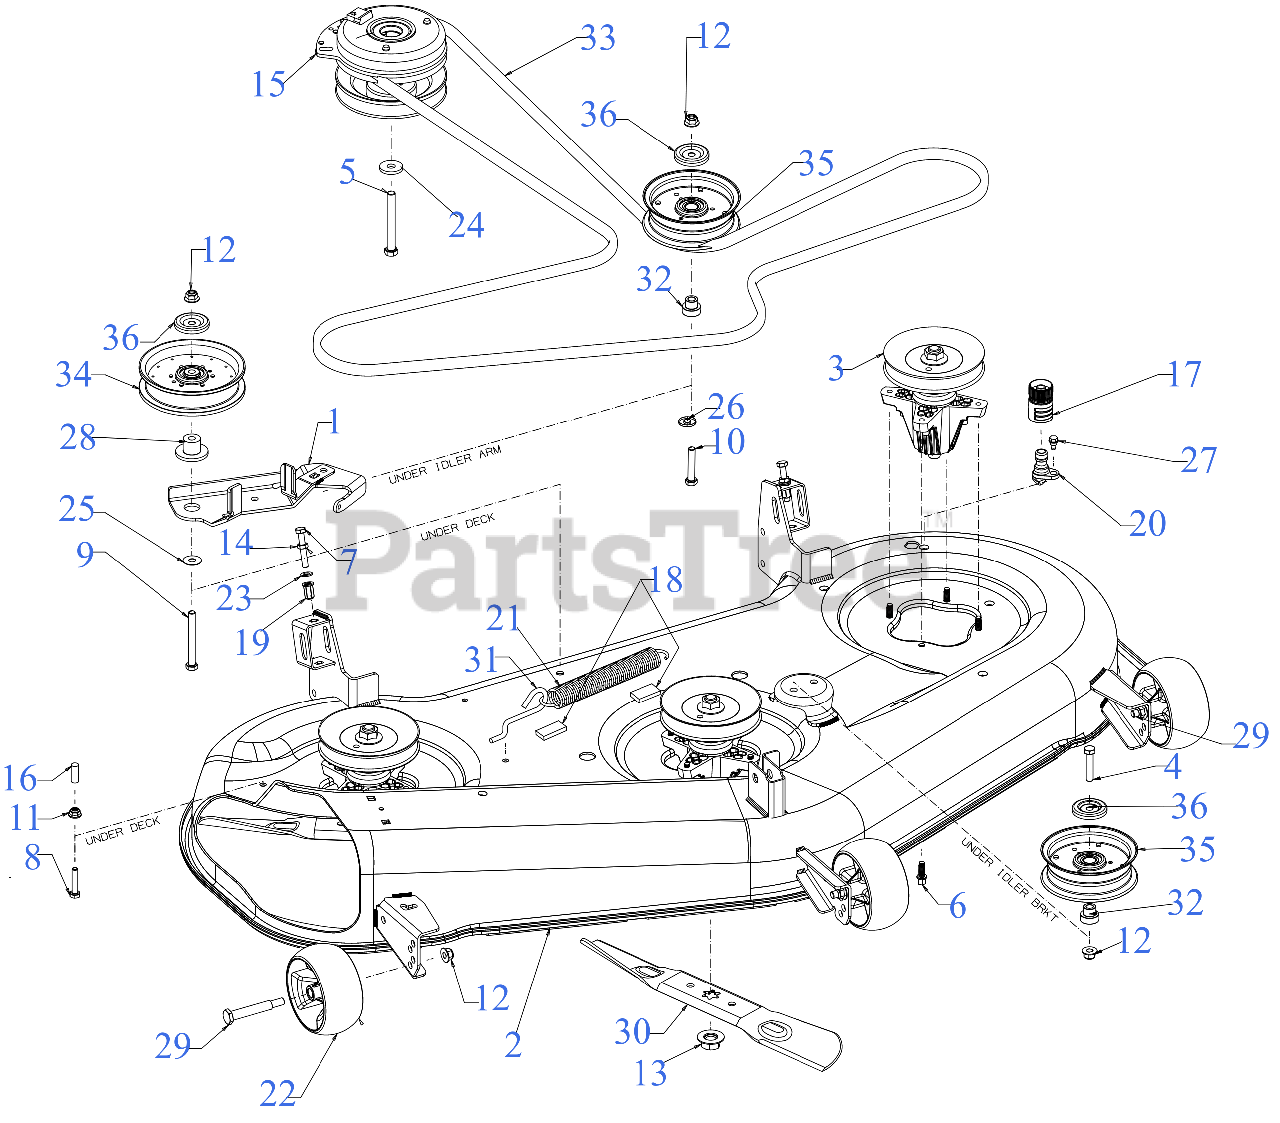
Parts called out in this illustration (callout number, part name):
1	DECK IDLER ASSEMBLY
2	54" DECK SHELL
3	SPINDLE ASSEMBLY
3	Cub Cadet 54" SPINDLE (06978 W/HDW)
4	HEX SCREW 3/8-16 x 1.75 GR5
5	SCREW 7/16-20 x 3.5 GR5
6	SCREW 5/16-18 x .875
7	SCREW-FULL THREAD 5/16-18 GR5
8	SCREW 5/16-18 x 1.5 LG
9	SCREW 3/8-16 x 3.25 GR8
10	SCREW 3/8-16 x 2.0 GR5
11	FLANGE LOCK NUT 5/16-18
13	HEX NUT
14	HEX NUT
15	ELECTRIC PTO CLUTCH
16	VINYL CAP
17	WATER NOZZLE ADAPTER
18	FOAM TAPE .75" WIDE x .25" THICK
19	NUT RIVET 5/16-18
20	DECK WASH NOZZLE
21	EXTENSION SPRING
22	DECK WHEEL
22	WHEELS-DELUXE 5"
23	FLAT WASHER .344 x .62
24	FLAT WASHER .445 x 1.248 x .170
25	FLAT WASHER
26	WASHER
27	SHOULDER SCREW 1/4-20 x .50
28	SHOULDER SPACER
29	SHOULDER BOLT .50 x 2.5 x 3/8 -16
30	18.61" BLADE (2N1)
30	Cub Cadet 54" HI LIFT BLADE SET
30	Genuine Factory Parts 54" BLADE SET
30	54" 6 PT STAR LOW LIFT/SAND BLADE
30	Cub Cadet 54" LOWLIFT BLADE SET
30	Genuine Factory Parts 54" LOWLIFT BLADE SET
30	54" 6 PT STAR XTREME MULCH BLADE
30	Cub Cadet 54" XTREME BLADE SET
30	Genuine Factory Parts 54" XTREME MULCH BLADE SET
31	DECK SPRING HOOK
32	SHOULDER SPACER
33	V-BELT B SEC x 148.25
33	Cub Cadet 54" DECK DRIVE BELT
33	Troy-Bilt 54" DECK DRIVE BELT
34	FLAT IDLER PULLEY
35	IDLER PULLEY 4.50" DIA
36	IDLER PULLEY CAP
